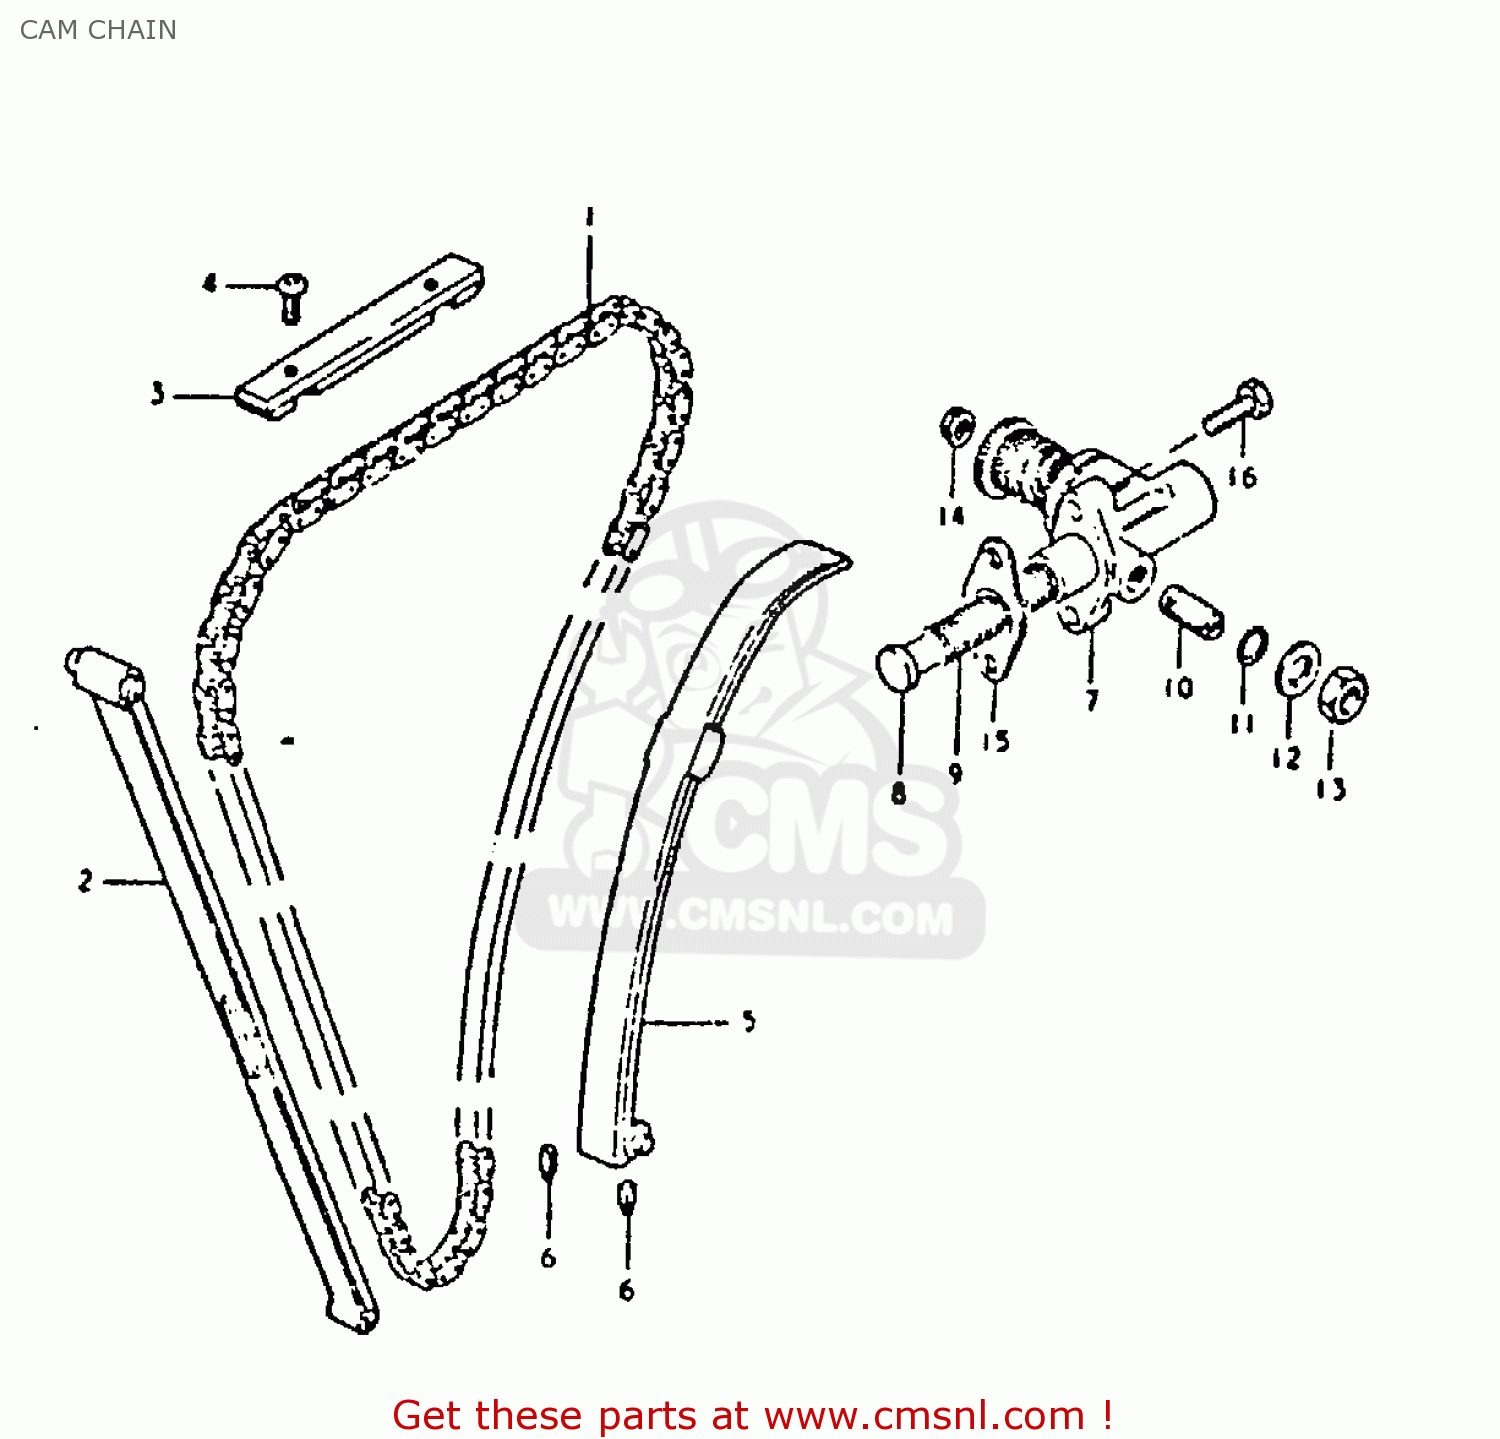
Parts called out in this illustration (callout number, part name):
1	CHAIN,CAMSHAFT DRIVE
2	GUIDE,CAM CHAIN NO.1
3	GUIDE,CAM CHAIN NO.3
4	SCREW
5	TENSIONER,CAM CHAIN
6	CUSHION,CAM CHAIN TENSIONER
7	ADJUSTER ASSEMBLY,TENSIONER
8	ROD,PUSH
9	SPRING
10	SCREW
11	O-RING
12	WASHER
13	NUT
14	NUT
15	GASKET,TENSIONER ADJUSTER (MCA)
16	SCREW (6X25)
